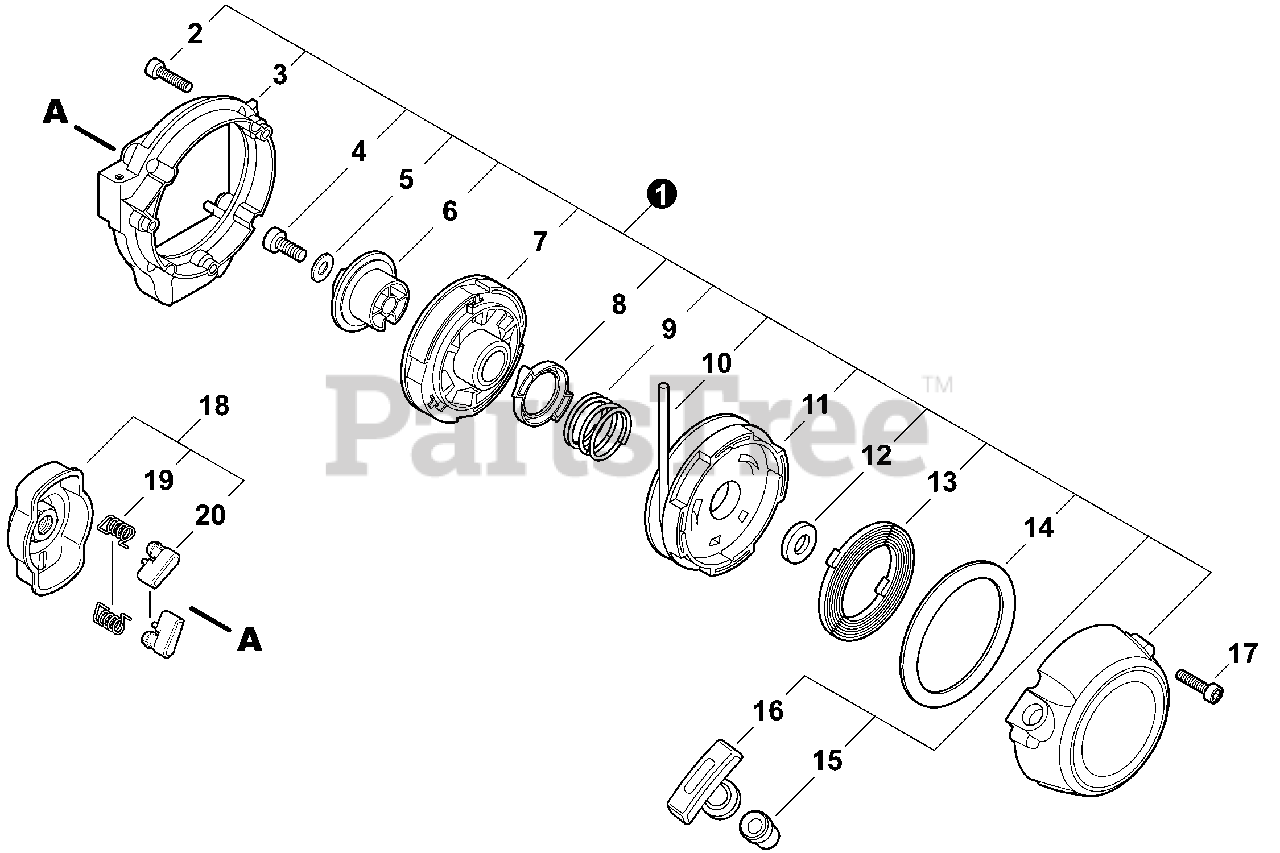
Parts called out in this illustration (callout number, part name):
1	STARTER ASSY, RECOIL
2	BOLT, TORX 4×16
3	BRACKET, STARTER
4	BOLT, TORX 5×12
5	WASHER 5.5×12×0.8
7	CLUTCH ASSY
10	ROPE, STARTER 3×900
12	COLLAR 8
13	SPRING, RECOIL
14	PLATE, STARTER
15	GUIDE, ROPE
16	GRIP, STARTER
17	BOLT, TORX 4×16
18	PAWL ASSY, STARTER
19	SPRING, RETURN
20	PAWL, STARTER - BLACK
